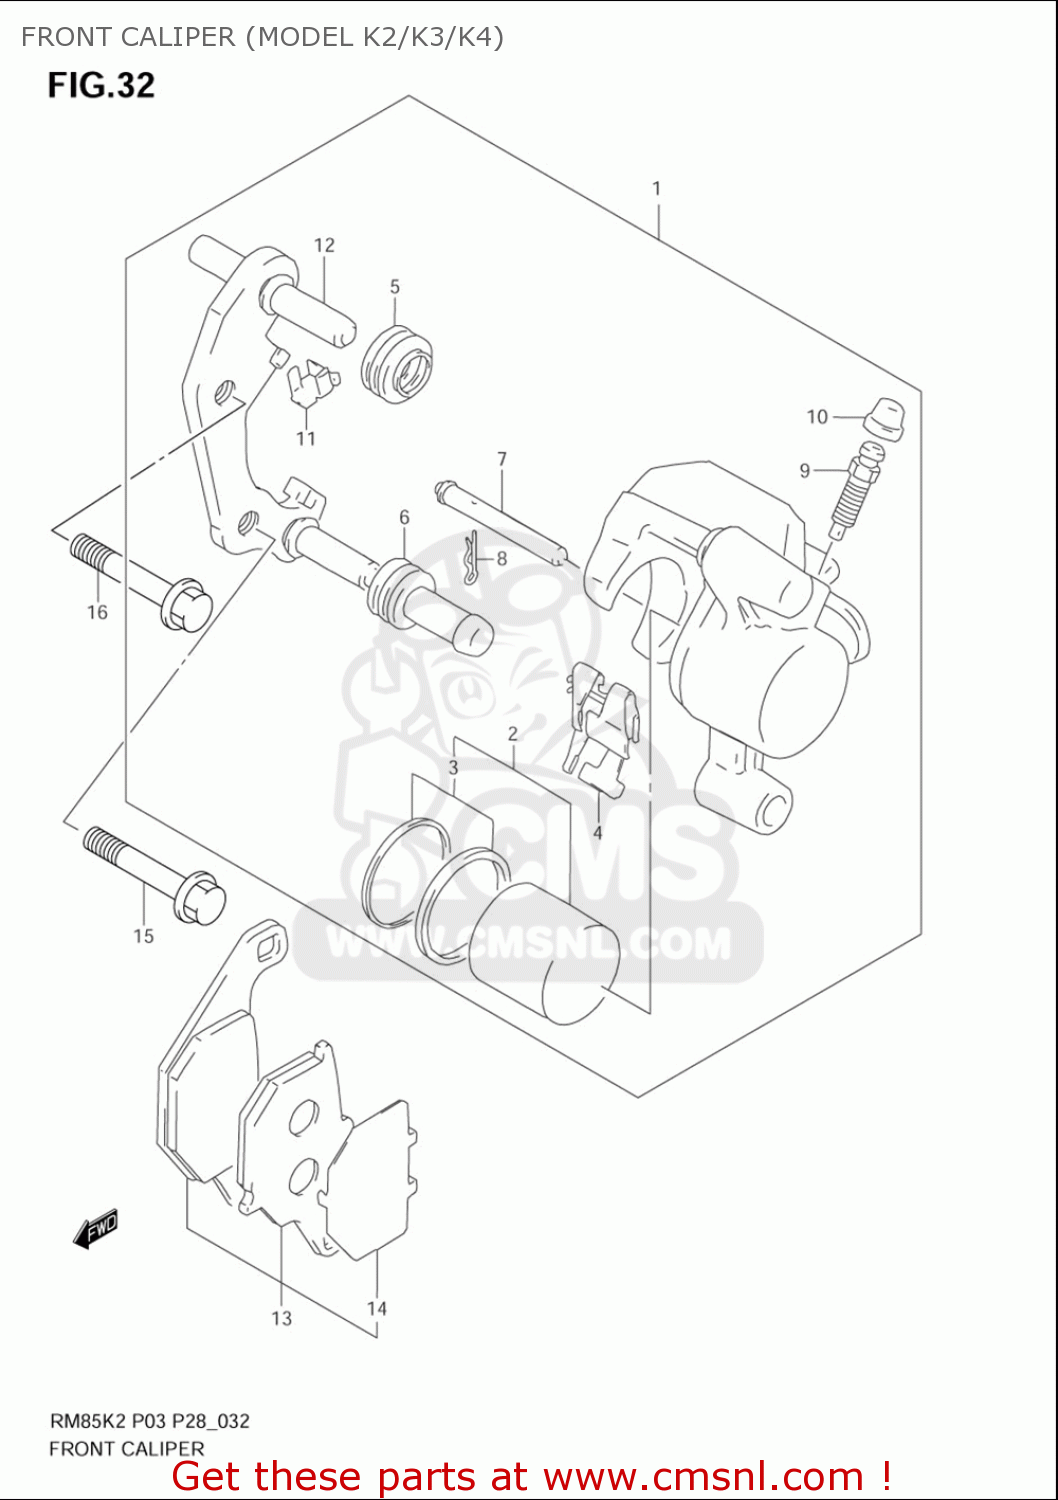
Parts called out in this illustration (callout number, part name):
1	CALIPER ASSY,FR,L
2	PISTON SET
3	SEAL SET,PISTON
4	SPRING,PAD
5	BOOT,AXLE
6	INSULATOR,AXLE
7	PIN,PAD
8	CLIP,PAD PIN
9	BLEEDER
10	CAP,BLEEDER PLUG
11	GUIDE,PAD
12	CARRIER,CALIPER,L
13	PAD & SHIM SET (NAS)
14	SHIM,PAD
15	BOLT(8X48)
16	BOLT(8X32)
